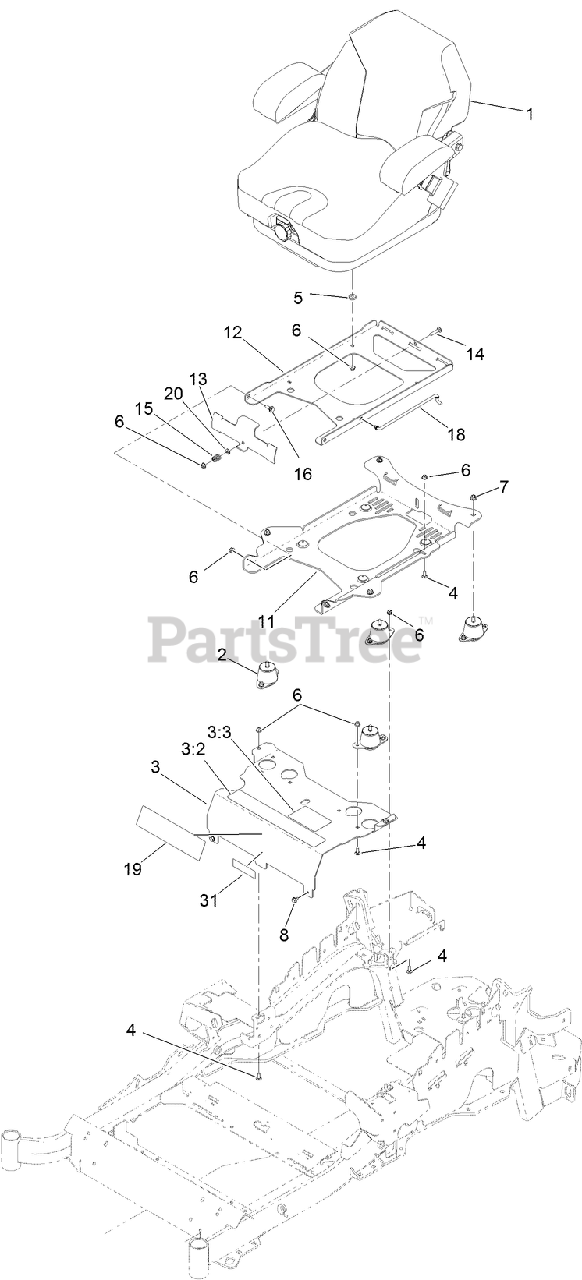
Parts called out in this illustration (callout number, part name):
1	SUSPENSION SEAT ASM
2	ISOLATOR-SEAT
3	SEAT MOUNT ASM
3:2	DECAL-CONSOLE
3:3	DECAL-SERVICE AID
4	SCREW-CARR
5	SPACER-PIN, MOUNTING
6	NUT-HF, NI
7	NUT-HF, NI
8	SCREW
11	PLATE-TILT, SEAT SUPPORT
12	PLATE-FRAME, SEAT
13	PLATE-LATCH, SEAT
14	BOLT-CARR
15	SPRING-COMPRESSION
16	SCREW-SHOULDER
18	ROD-PROP
20	WASHER-PLAIN
31	DECAL-EFI PROPANE
